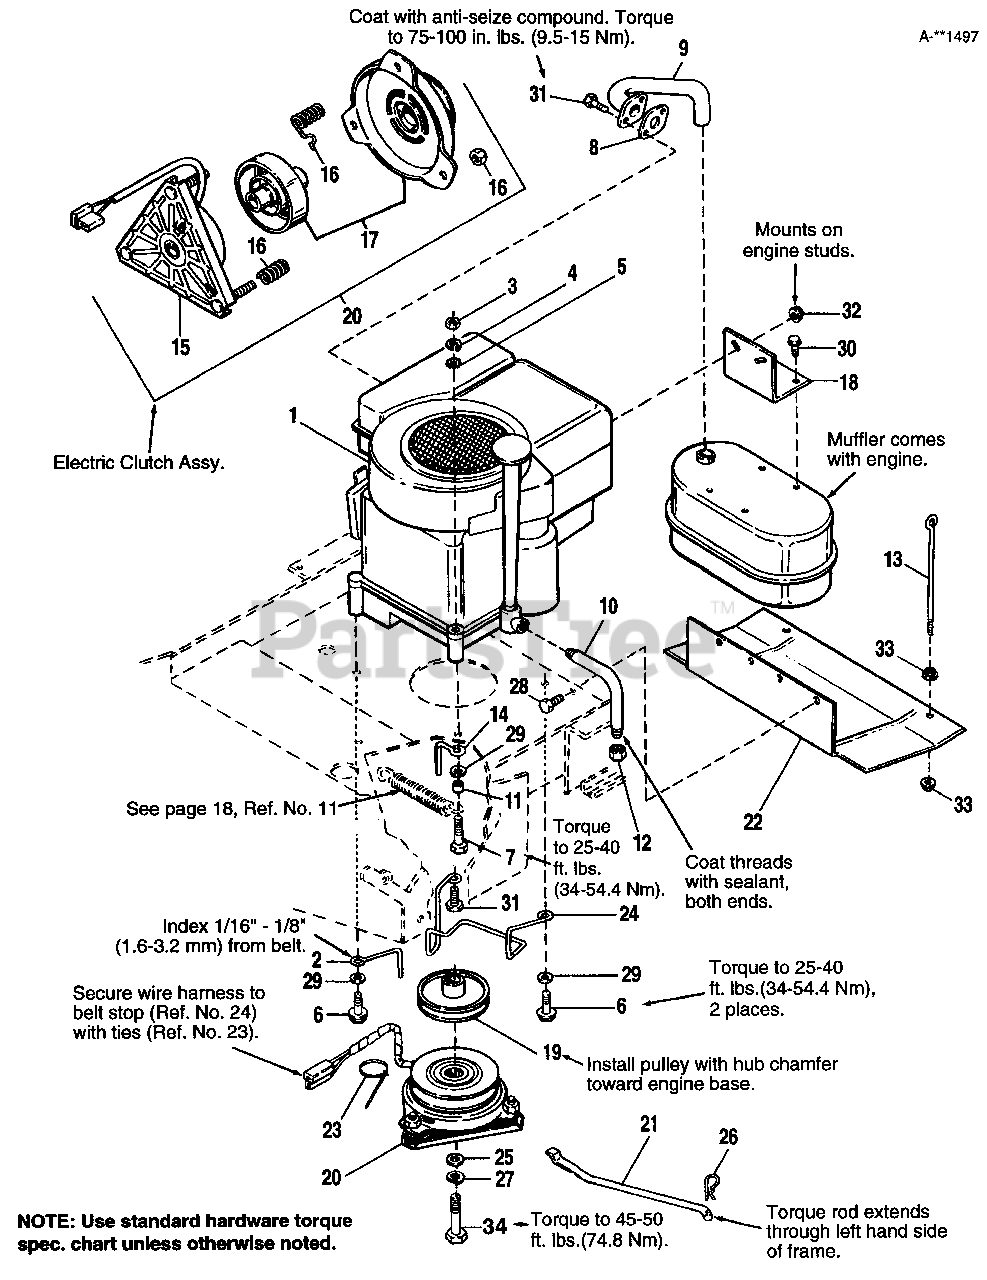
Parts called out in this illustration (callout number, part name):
1	ENGINE, 12 HP, Briggs & Stratton
3	NUT, Hex, 3/8-16
4	LOCKWASHER, 3/8
5	LOCKWASHER, Ext. Tooth, 3/8
6	SCREW, Taptite, 3/8-16 x 1-1/2
7	SCREW, Taptite, 3/8-16 x 2-1/2
8	GASKET, Muffler
9	PIPE, Exhaust
10	DRAIN, Oil
12	CAP, Hex, 3/8
13	ROD, Battery Hold Down
15	FIELD ASSY., Clutch
16	ACCESSORY KIT
17	ROTOR ASSY/ARMATURE ASSY. KIT, Clutch
18	BRACKET, Muffler
19	PULLEY ASSY., Drive
20	ELECTRIC CLUTCH ASSY. (Incl. Ref. Nos. 15-17)
21	ROD, Torque
22	HEAT SHIELD ASSY.
25	WASHER, 7/16
26	CLIP, Hair Pin
27	LOCKWASHER, 7/16
28	SCREW, Taptite, 5/16-18 x 1/2
29	WASHER, 3/8
30	SCREW, Taptite, 1/4-20 x 5/8
31	SCREW, Whizlock, 5/16-18 x 3/4
32	NUT, Hex, Whizlock, 5/16-18
33	NUT, Flange, Whizlock, 1/4-20
34	CAPSCREW, Hex, 7/16 x 3-1/4
